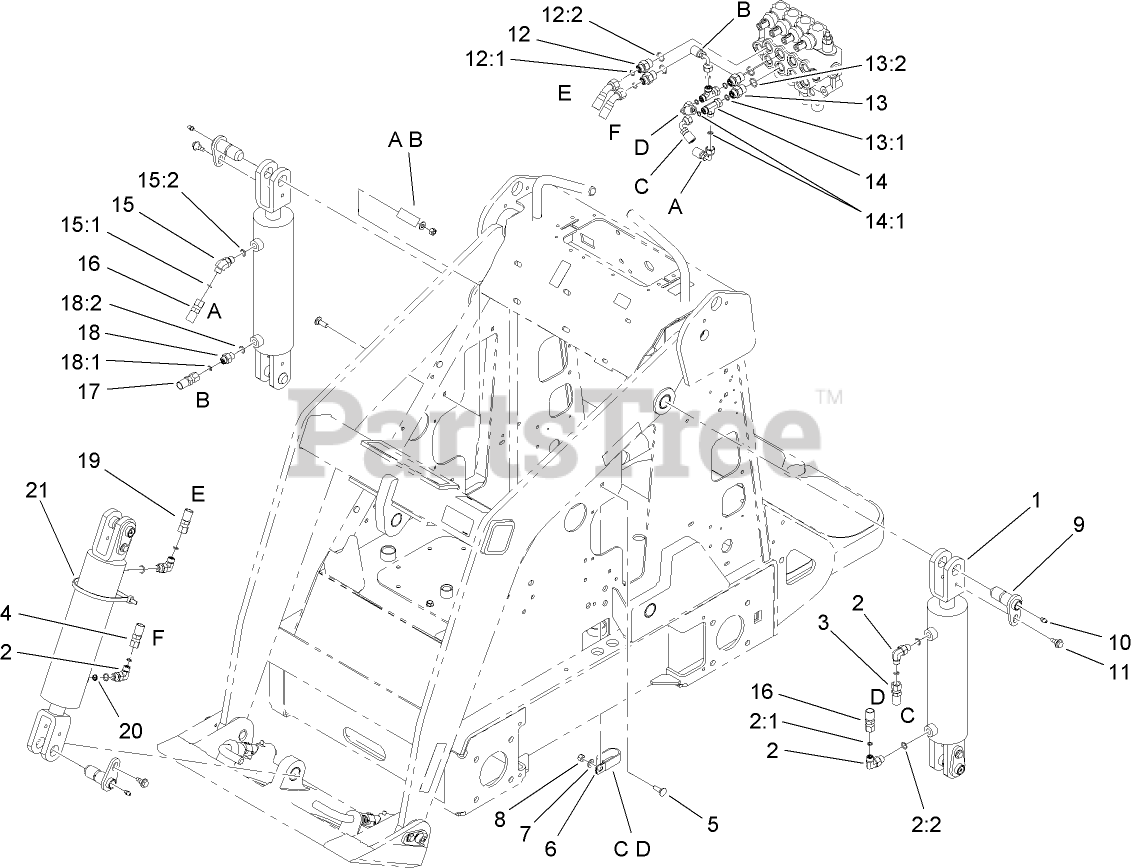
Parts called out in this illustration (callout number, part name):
1	HYD CYLINDER ASM
2	FITTING-ELBOW 90
2:1	O-RING
2:2	O-RING
3	HYD HOSE ASM
4	HOSE-HYD
5	BOLT-CARR
6	CLAMP-R, DOUBLE
7	WASHER-PLAIN
8	NUT-LOCK, NI
9	PIN-PIVOT
10	FITTING-GREASE
11	BOLT-SHOULDER
12	FITTING-STRAIGHT
12:1	O-RING
12:2	O-RING
13	FITTING-STR
13:1	O-RING
13:2	O-RING
14	FITTING-HYD
14:1	O-Ring
15	FITTING
15:1	O-RING
15:2	O-RING
16	HOSE-HYD
17	HOSE-HYD, RIGHT
18	FITTING-STRAIGHT
18:1	O-RING
18:2	O-RING
19	HOSE-HYD
20	ORIFICE-PORT INSERT, ONE WAY
21	TIE-CABLE
